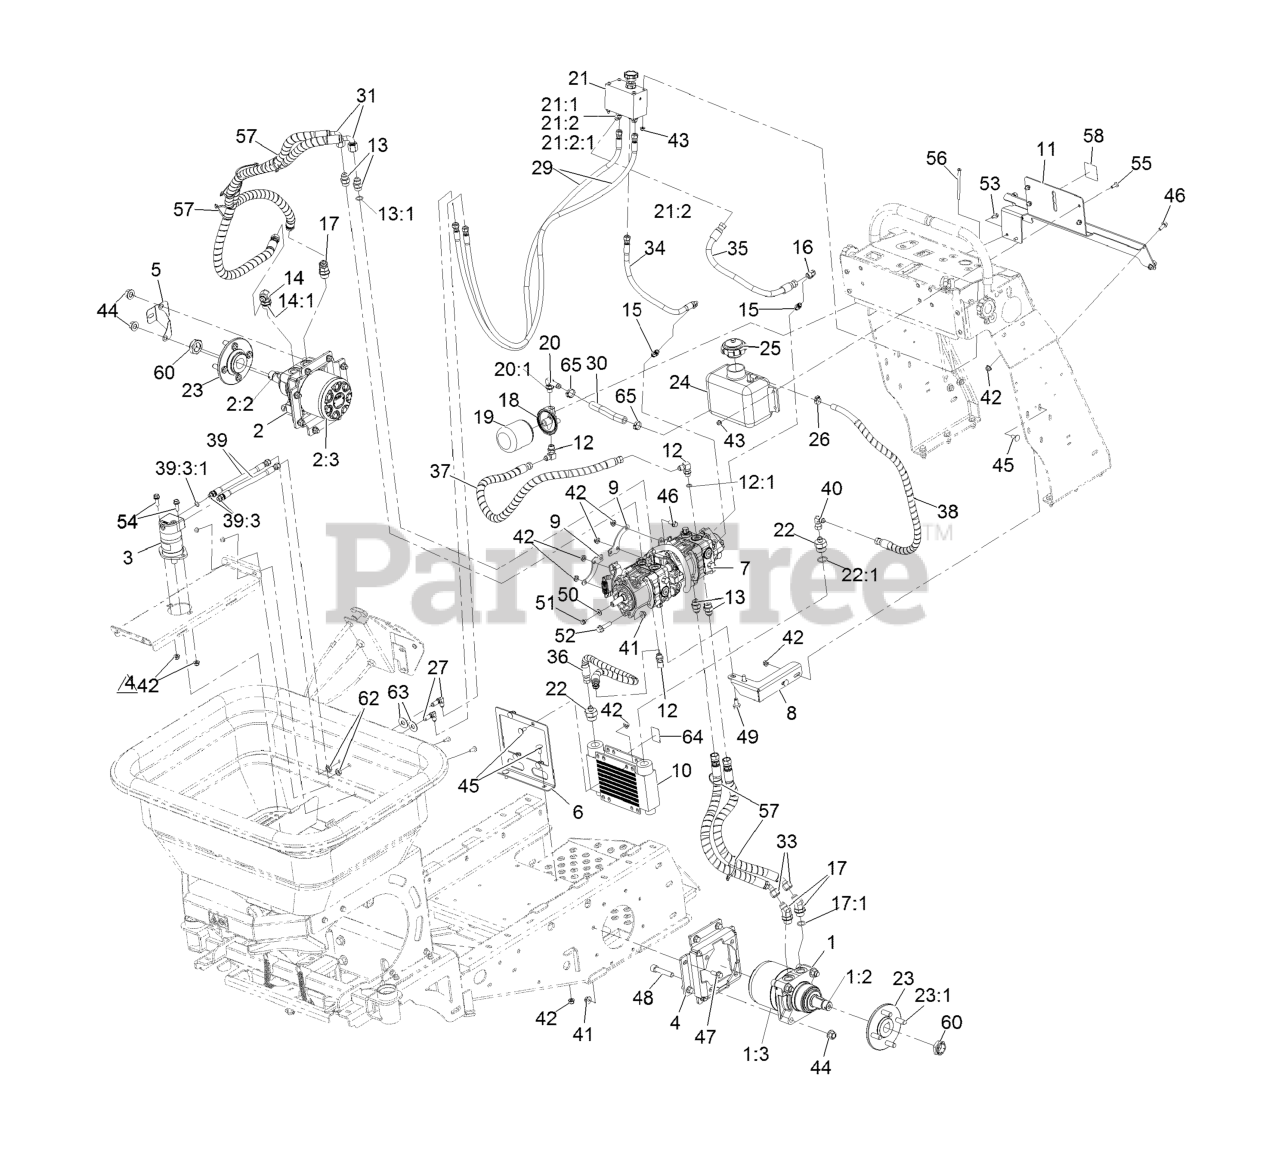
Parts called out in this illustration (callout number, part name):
1	MOTOR, LH WHEEL
1:2	KEY-WOODRUFF
1:3	SEAL KIT
2	MOTOR, RH WHEEL
2:2	KEY-WOODRUFF
2:3	SEAL KIT
3	MOTOR-HYDRAULIC, SPREADER
4	Mount-Motor, Wheel
5	BRACKET-HOPPER, SPEEDOMET
6	Mount-Cooler
7	PUMP-TANDEM
8	Bracket-Support, Hydro Pump
9	Extension, Hydro Pump
10	COOLER-OIL
11	Mount, Hydraulic Tank And Filter
12	FITTING-ELBOW, 90 DEG
12:1	O-RING
13	FITTING-STRAIGHT
13:1	O-RING
14	FITTING-90 DEG
14:1	O-RING
15	FITTING-STRAIGHT
16	FITTING-90 SWIVEL
17	FITTING-ELBOW, 45 DEG
17:1	O-RING
18	HEAD-FILTER
19	FILTER-25 MICRON, BI-DIRECTIONAL
20	FITTING-ELBOW, 90
20:1	O-RING
21	Manifold-Flow Control, Hopper
21:2	FITTING-ELBOW, 45 DEG
21:2:1	O-RING
22	ADAPTER-STRAIGHT
22:1	O-RING
23	HUB-WHEEL
23:1	STUD-1/2-20 X 1.55
24	TANK-HYDRAULIC, PLASTIC
25	Cap-Vented
26	CLAMP-OETIKER, 167
27	FITTING-ELBOW, 90
29	Hose ASM, HYD HP
30	HOSE-HYDRAULIC
31	HOSE ASM-HYD HP
33	HOSE ASM-HYD HP
34	Hose ASM-HYD HP
35	Hose ASM, HYD LP
36	Hose ASM, HYD LP
37	Hose ASM, HYD LP
38	Hose ASM, HYD LP
39	Hose ASM-HYD HP
39:3	Fitting-Straight, Rigid
39:3:1	O-RING
40	ELBOW-SWIVEL, 90 DEG
41	Nut-Hex Flange
42	Nut-Hex Flange
43	Nut-Hex Flange
44	Nut-Lock 1/2-13
45	SCREW-CARR
46	SCREW-HHF
47	SCREW-HHF
48	Screw-HSH
49	SCREW-HHF
51	SCREW-HHF
52	SCREW-HHF
53	SCREW-HHF
54	SCREW-HHF
55	Screw-Hsbhf
56	Screw-HSBH
57	TIE-CABLE
58	DECAL-OIL
60	LOCKNUT
62	Nut-Jam
63	Washer-SS, 1.25 OD, .503 ID
64	DECAL-WARNING
65	CLAMP-OETIKER, 167
